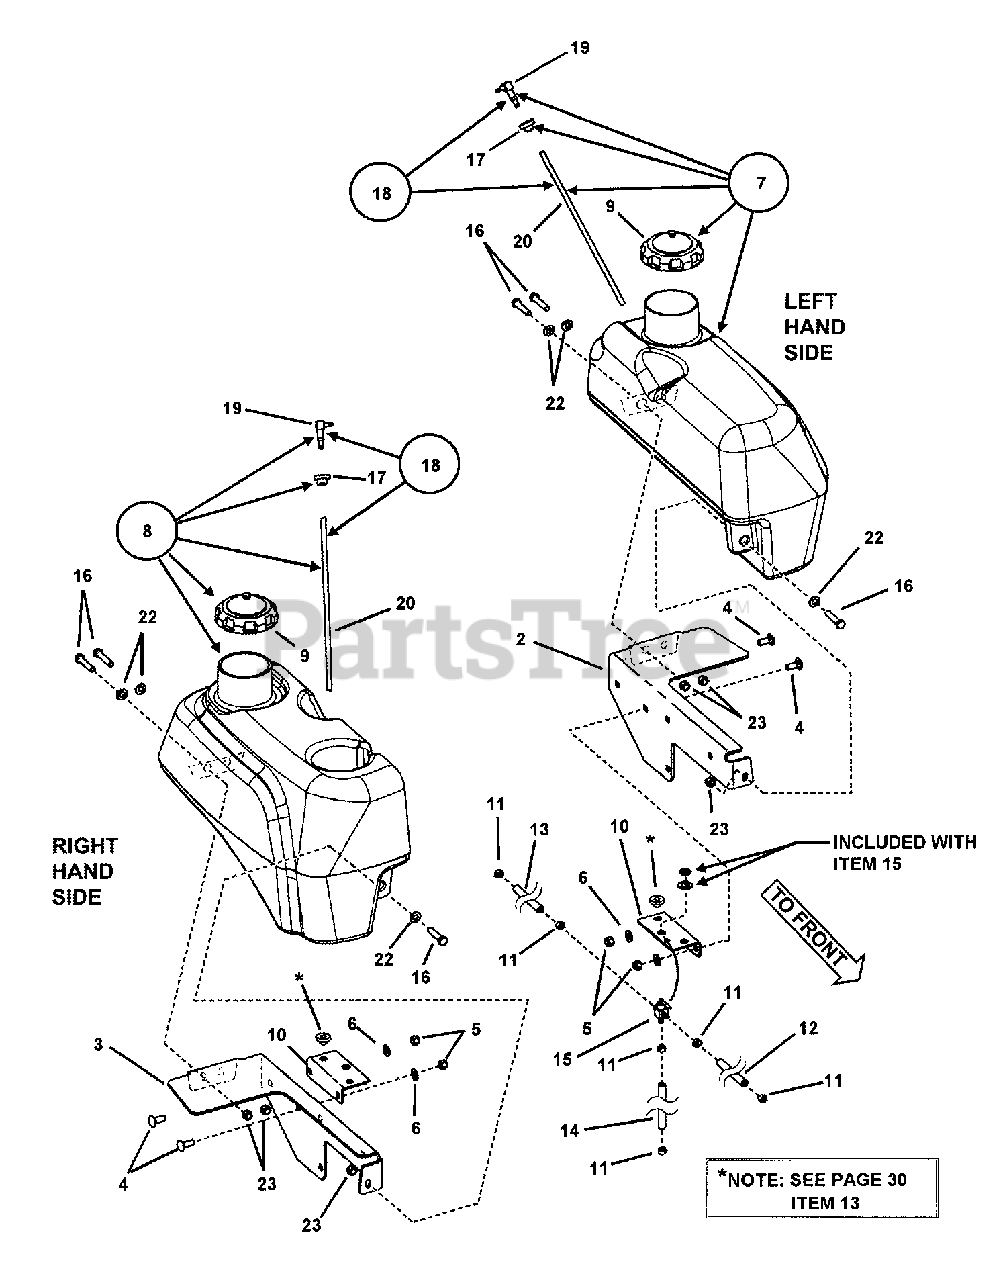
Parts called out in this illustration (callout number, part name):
2	WELDMENT, Left Hand Fuel Tank Bracket
3	WELDMENT, Right Hand Fuel Tank Bracket
4	BOLT, 3/8-16 x 1" Square Neck Carriage GR5
5	NUT, 3/8-16 HEX NYLON LOCK
6	WASHER, 3/8" Flat
7	ASSEMBLY, Fuel Tank, Left Hand
8	ASSEMBLY, Fuel Tank, Right Hand
9	CAP, 3-1/2" Fuel
10	BRACKET, Valve Mount
11	CLAMP, 7/16" Fuel Hose
12	HOSE, 1/4" I.D. x 3'-7.5" Long Fuel (R.H.)
13	HOSE, 1/4" I.D. x 1'-8" Long Fuel (L.H.)
14	HOSE, 1/4" I.D. x 1' Long Fuel
15	ASSEMBLY, 3-Way Fuel Valve
16	SCREW, 7/16-14 x 2" Hex Head Cap, GR5
17	GROMMET
18	ASSEMBLY, Fuel Pickup (Incl. 74835 & 75106, one each)
19	ELBOW, 90 Degree
20	DIP TUBE
22	WASHER, 1/2" Flat SAE
23	NUT, 7/16-14 HEX NYLON LOCK
